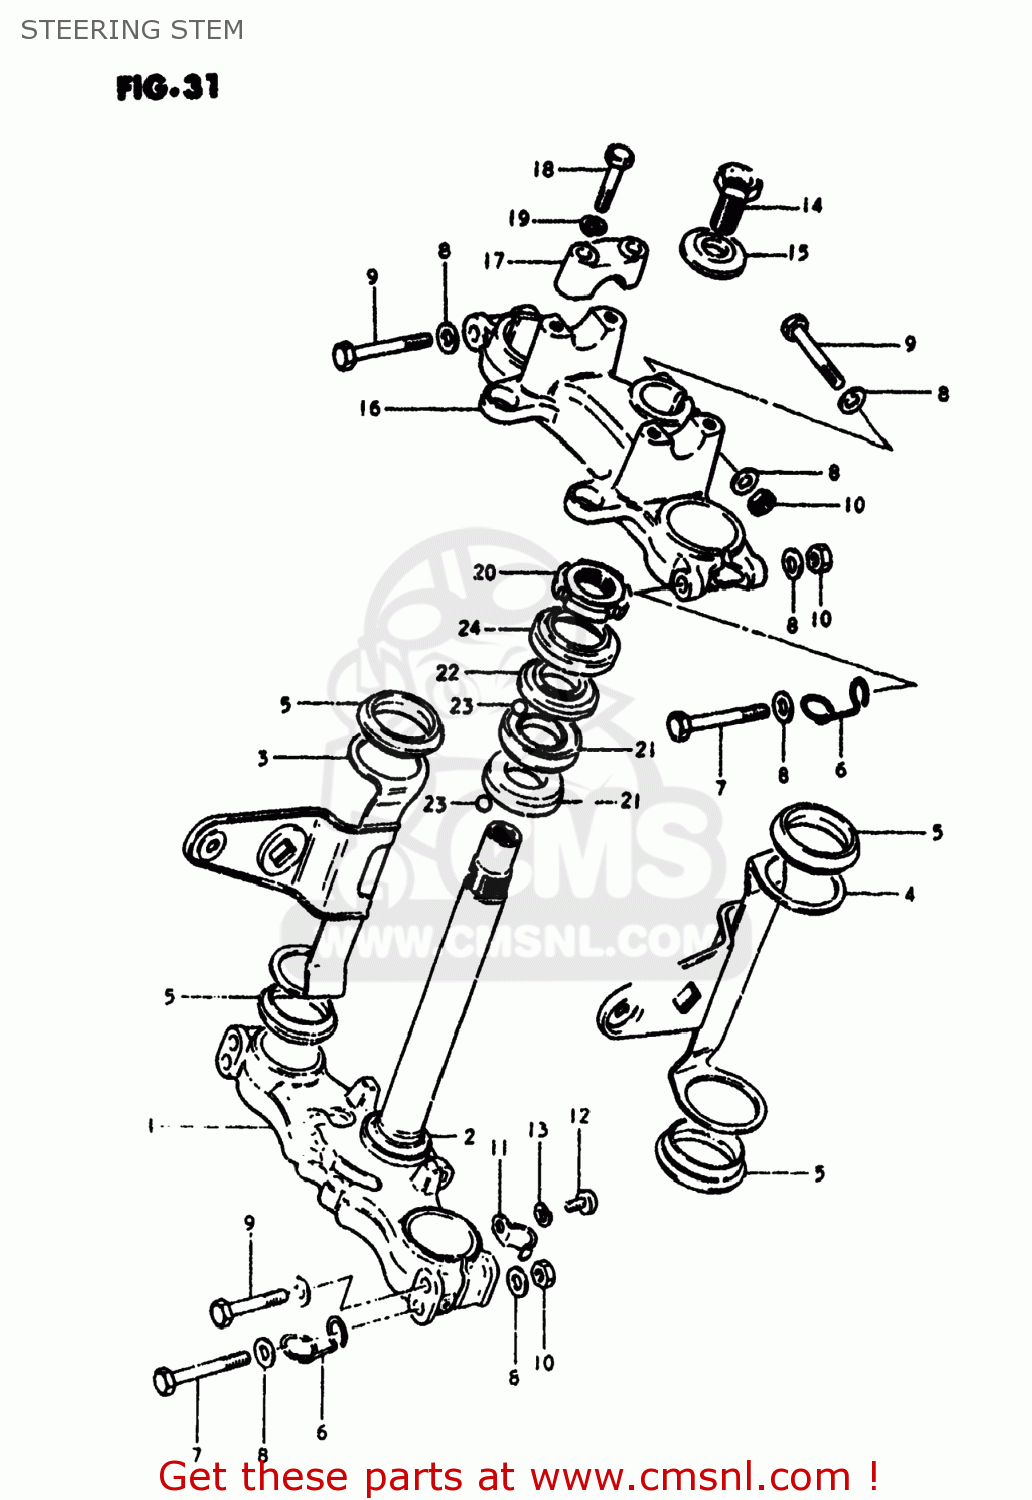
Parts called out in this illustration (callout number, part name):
1	STEM,STEERING
2	RACE,STEERING OUTER LWR
3	BRACKET,HEADLAMP,RIGHT
4	BRACKET,HEADLAMP,LEFT
5	CUSHION,HEADLAMP BRACKET
6	GUIDE,CABLE
7	BOLT
8	WASHER
9	BOLT 8X55
10	NUT
11	CLIP,BRAKE CABLE
12	SCREW
13	LOCK WASHER
14	BOLT,STEERING STEM HEAD
15	WASHER
16	HEAD,STEERING STEM
17	HOLDER,HANDLEBAR
18	BOLT
19	LOCK WASHER
20	NUT,STEERING STEM(25X44X10)
21	LACE,STEERING INNER LWR
22	LACE,STEERING OUTER UPR
23	BALL
24	DUST SEAL,STEERING UPR
